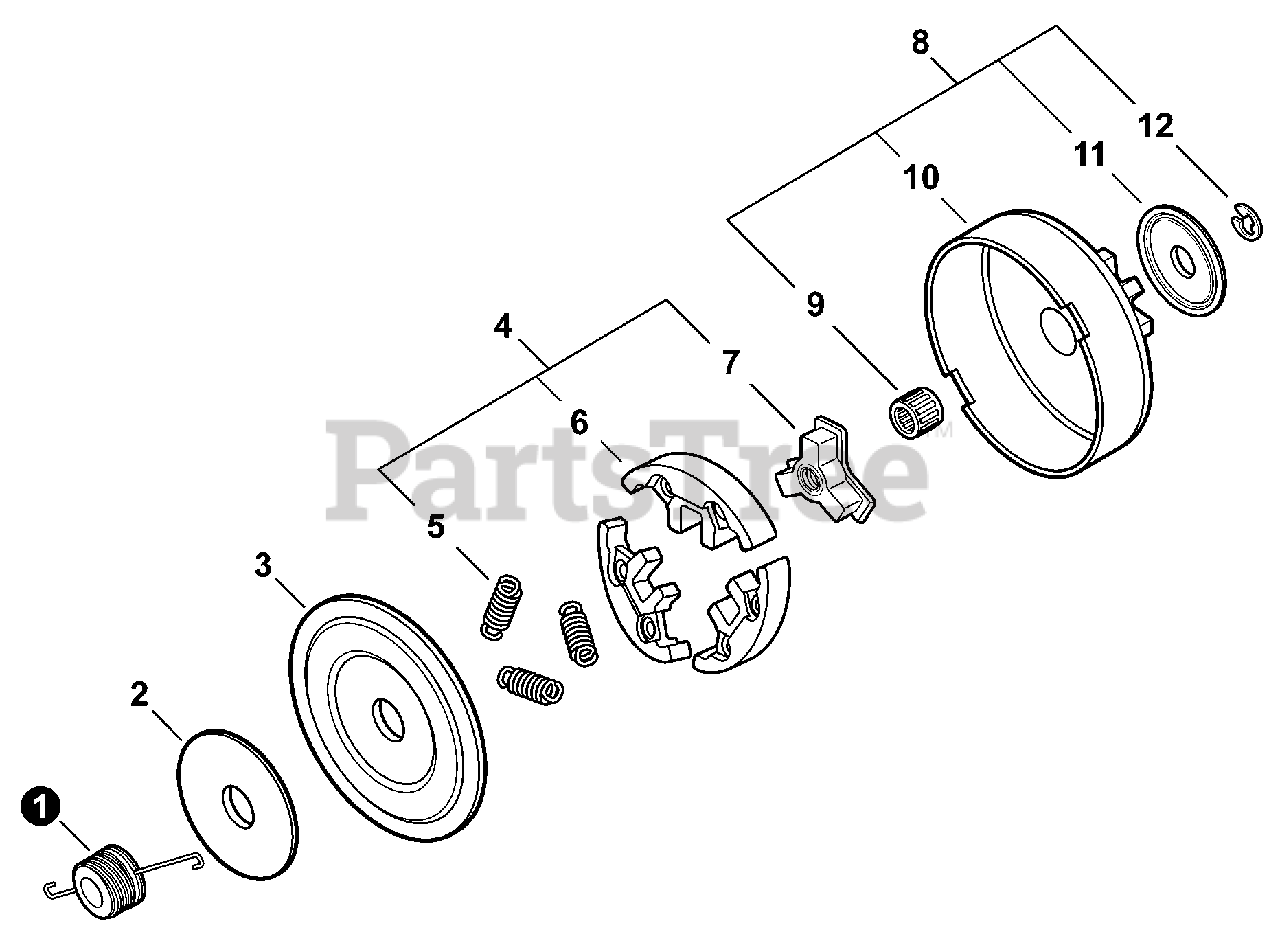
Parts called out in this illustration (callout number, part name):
1	GEAR, WORM
2	PLATE, CLUTCH - SMALL
3	PLATE, CLUTCH - LARGE
4	CLUTCH ASSY
5	SPRING, CLUTCH
6	SHOE SET, CLUTCH (3PCS)
7	HUB, CLUTCH
8	CLUTCH KIT
9	BEARING, NEEDLE 8
10	DRUM, CLUTCH
11	WASHER 8.2×31×0.8
